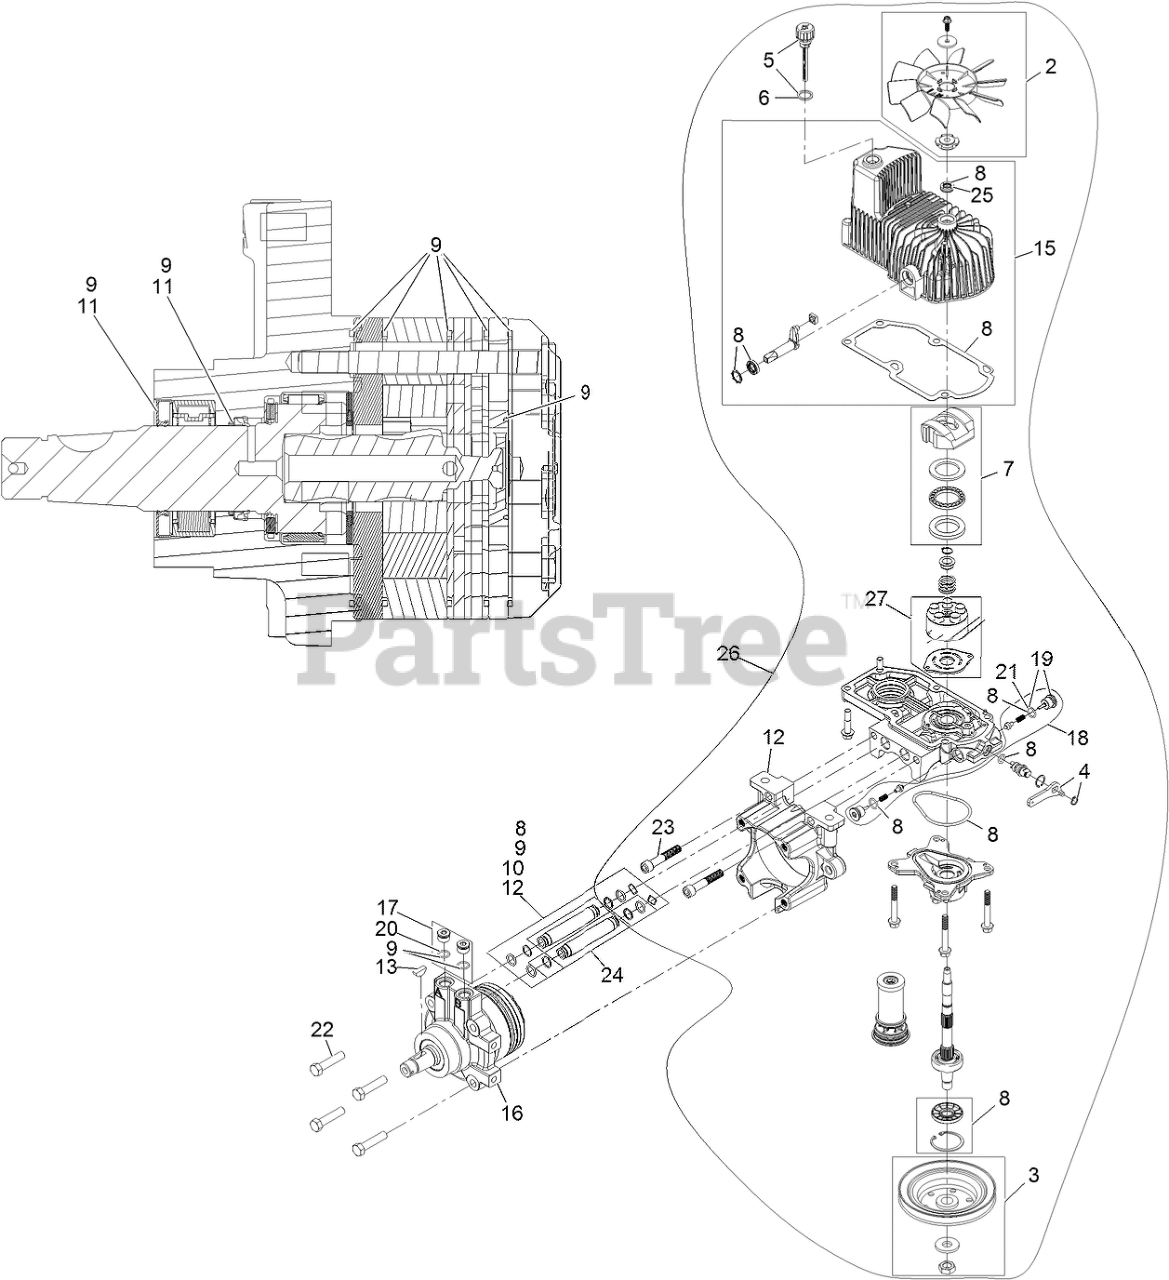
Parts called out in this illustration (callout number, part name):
2	Kit, 7.8 In Fan
3	PULLEY KIT
4	HANDLE-BYPASS VALVE, HYDRO
5	DIPSTICK-HYDRO W/GASKET
6	GASKET-DIPSTICK, HYDRO
7	SWASH BLOCK KIT
8	Kit, Pump Seal
9	MOTOR SEAL KIT
10	TUBE SEAL KIT
11	OUTPUT SHAFT SEAL KIT
12	NOSE CUP-UHT
13	KEY-WOODRUFF
15	Kit, Housing-Hydro LH
16	MOTOR-HYDRAULIC LH 240CC
17	MAGNETIC PLUGS SERVICE KIT
18	ASM, CHECK VALVE
19	PLUG-CHECK (W/O-RING)
21	O-RING-CHECK VALVE
22	SCREW HH
23	SCREW-HSH
24	HYDRAULIC TUBE KIT
25	SEAL-FAN DRIVE
26	Kit, Pump Section 12Cc LH
27	Kit - 12Cc Port Plate,Rotate Grp
